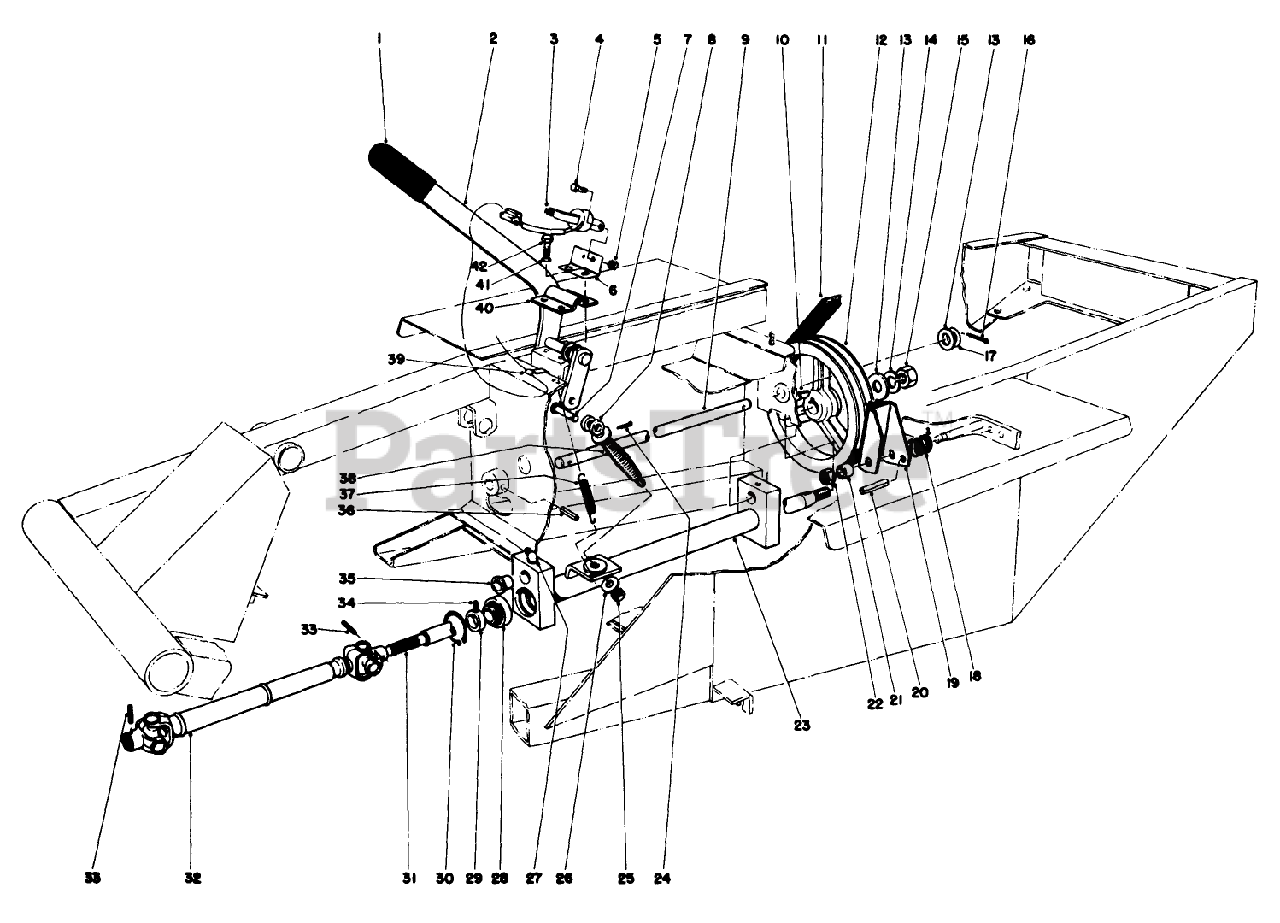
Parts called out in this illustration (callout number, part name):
1	GRIP-HANDLE
2	Lever P.T.O.
3	SWITCH ARM
4	SCREW-HH
5	NUT-LOCK, NI
6	SWITCH ARM MT
7	PIN-CLEVIS
8	YOKE END WA R
9	PIVOT PTO SHAFT
10	KEY-WOODRUFF
11	V-BELT
12	PULLEY-PTO
13	WASHER-FLAT
14	Lockwasher
15	NUT-HEX
16	PIN-COTTER
17	WASHER-THRUST
18	SPRING-ADJUSTMENT
19	PTO BRAKE ASM
20	PIN-ROLL
21	SPACER-SPRING, ANCHOR
22	NUT-LOCK, NI
23	Pivot-Power Take Off (Incl. Ref.#35)
24	PIN-COTTER
25	NUT-LOCK, NI
26	Washer
27	FITTING-GREASE
28	Bearing
29	Lock Collar (Incl. Ref.#34)
30	RING-SNAP, INTERNAL
31	PTO SHAFT
32	Universal Joint
32	Asm-Drive Shaft
33	PIN-ROLL
34	SCREW-SET, HSH
35	3/4IDX1LG FLANGE BSHG
36	PIN-ROLL, SLOTTED
37	SPRING-EXTENSION
38	SPRING-COMPRESSION
39	CLAMP-CASING
40	CLAMP-LEVER, PTO
41	WASHER-LOCK
42	SCREW-HH, TAP
